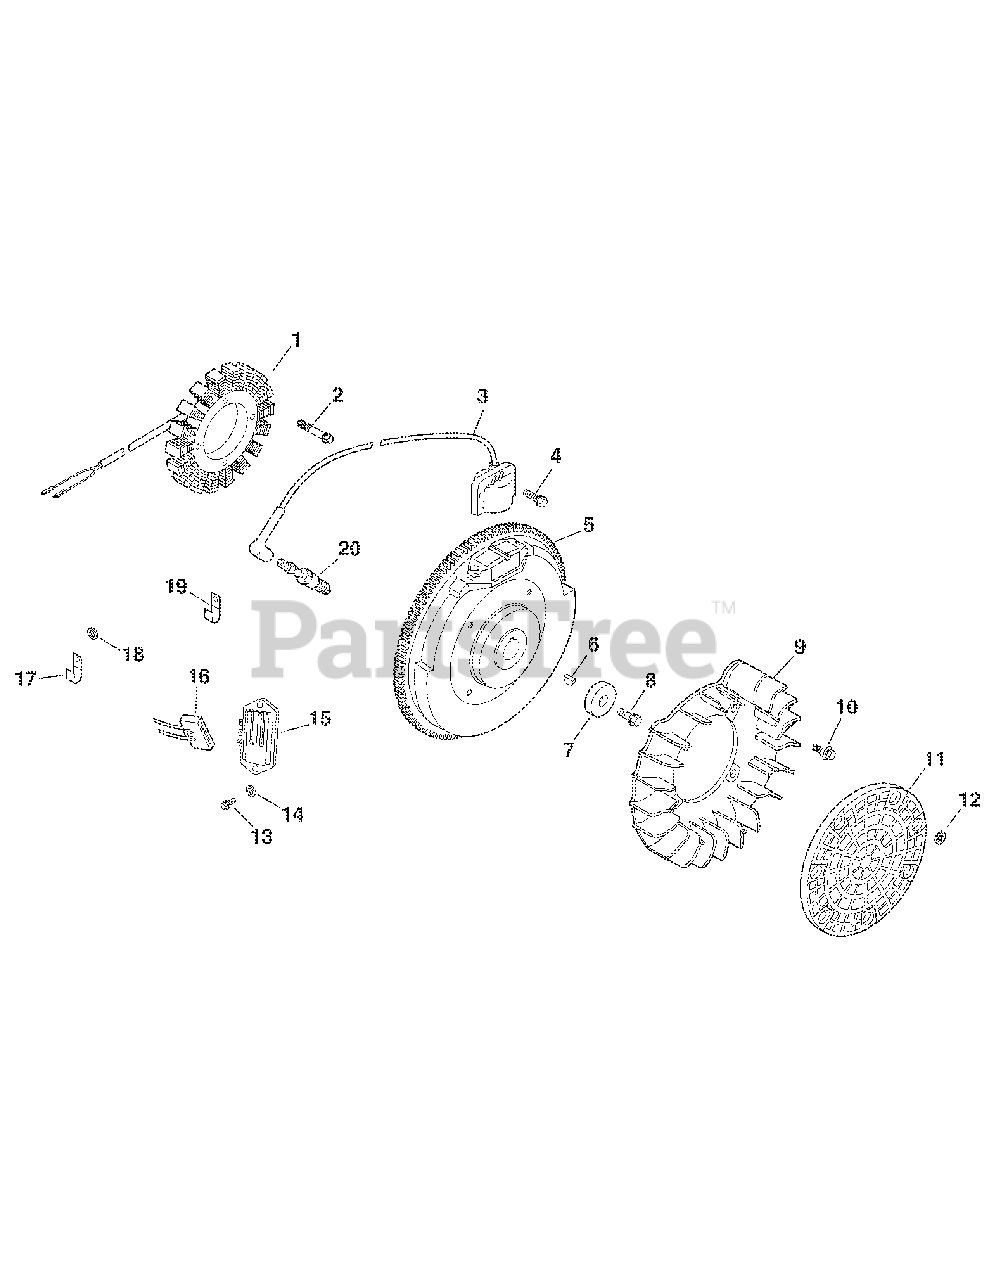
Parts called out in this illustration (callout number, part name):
1	Kit, 15 amp stator (Includes 2)
2	Screw, hex. Cap M5x0.8x25 (2)
3	Module, ignition (2)
4	Screw, hex. Flange M5x0.8x20 (4)
5	Flywheel
7	Washer, plain 3/8"
8	Screw, hex. Flange M10x1.5x46
9	Fan
10	Bolt, shoulder (4)
11	Screen, grass
12	Retainer, grass screen (3)
13	Screw, phillips hd. 11-16x7/8" (2)
14	Washer, plain 3/16" (2)
15	Rectifier-regulator 15 amp
16	Connector (3 contact)
17	Clip, cable
18	Washer, plain 1/4"
20	Spark Plug (2)
